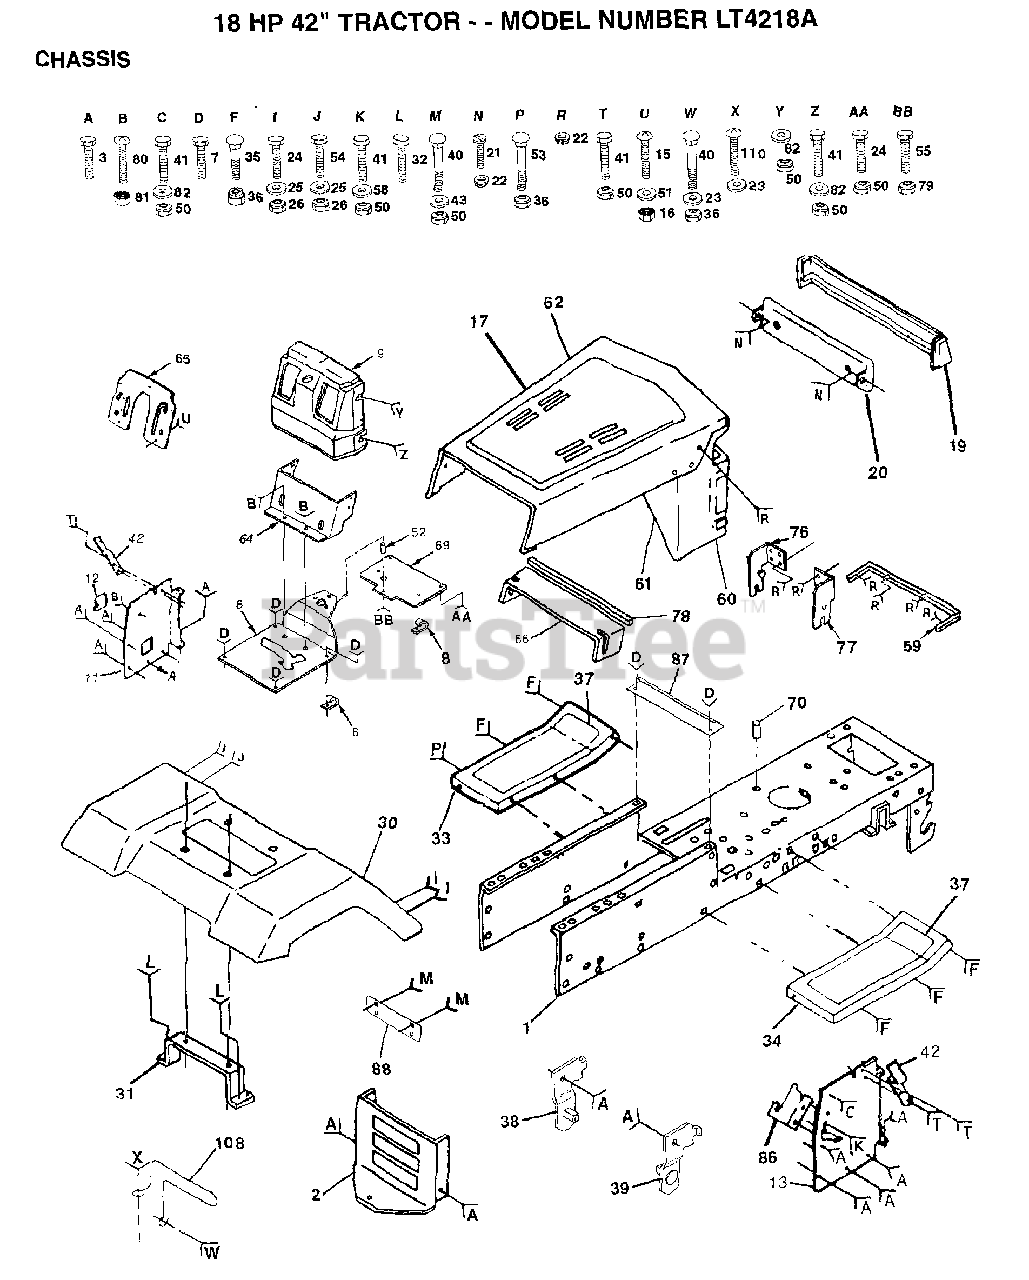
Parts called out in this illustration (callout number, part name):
3	SCREW
7	SCREW GTV
8	CLIP T
11	PANEL.DASH.LH
12	COVER ACCESS
13	PANEL DASH RH NOT
15	SCREW
16	NUT
17	HOOD/GRILLE ASM
21	SCREW SPECIAL
22	PAL NUT LT
23	WASHER HYT
25	WASHER
31	BRACKET SUPT FEND
32	SCREW
35	BOLT
37	FOOTREST PAD
38	BRACKET ASM LH
39	BRACKET ASM RH
40	BOLT D
41	BOLT
42	BRACKET.ASM.SUPT.
43	WASHER
50	NUT
51	WASHER PM
52	SPACER
55	BOLT
58	LOCKWASHER
59	STRAP FENDER ASM
60	GRILLE ASM WELD
61	ASSY-PANEL SIDE
62	PANEL SIDE LH ASM
65	PLATE DASH SILKSC
66	"BAFFLE,HOOD"
69	PLATE.SUPT.BATTER
76	BRACKET.RH
77	BRACKET.LH
78	FOAM STRIP T
79	NUT
80	SCREW
82	WASHER
87	SPACER FENDER LT
88	PLATE EXTEN FEND
108	MUFFLER GUARD
110	SCREW GTV
